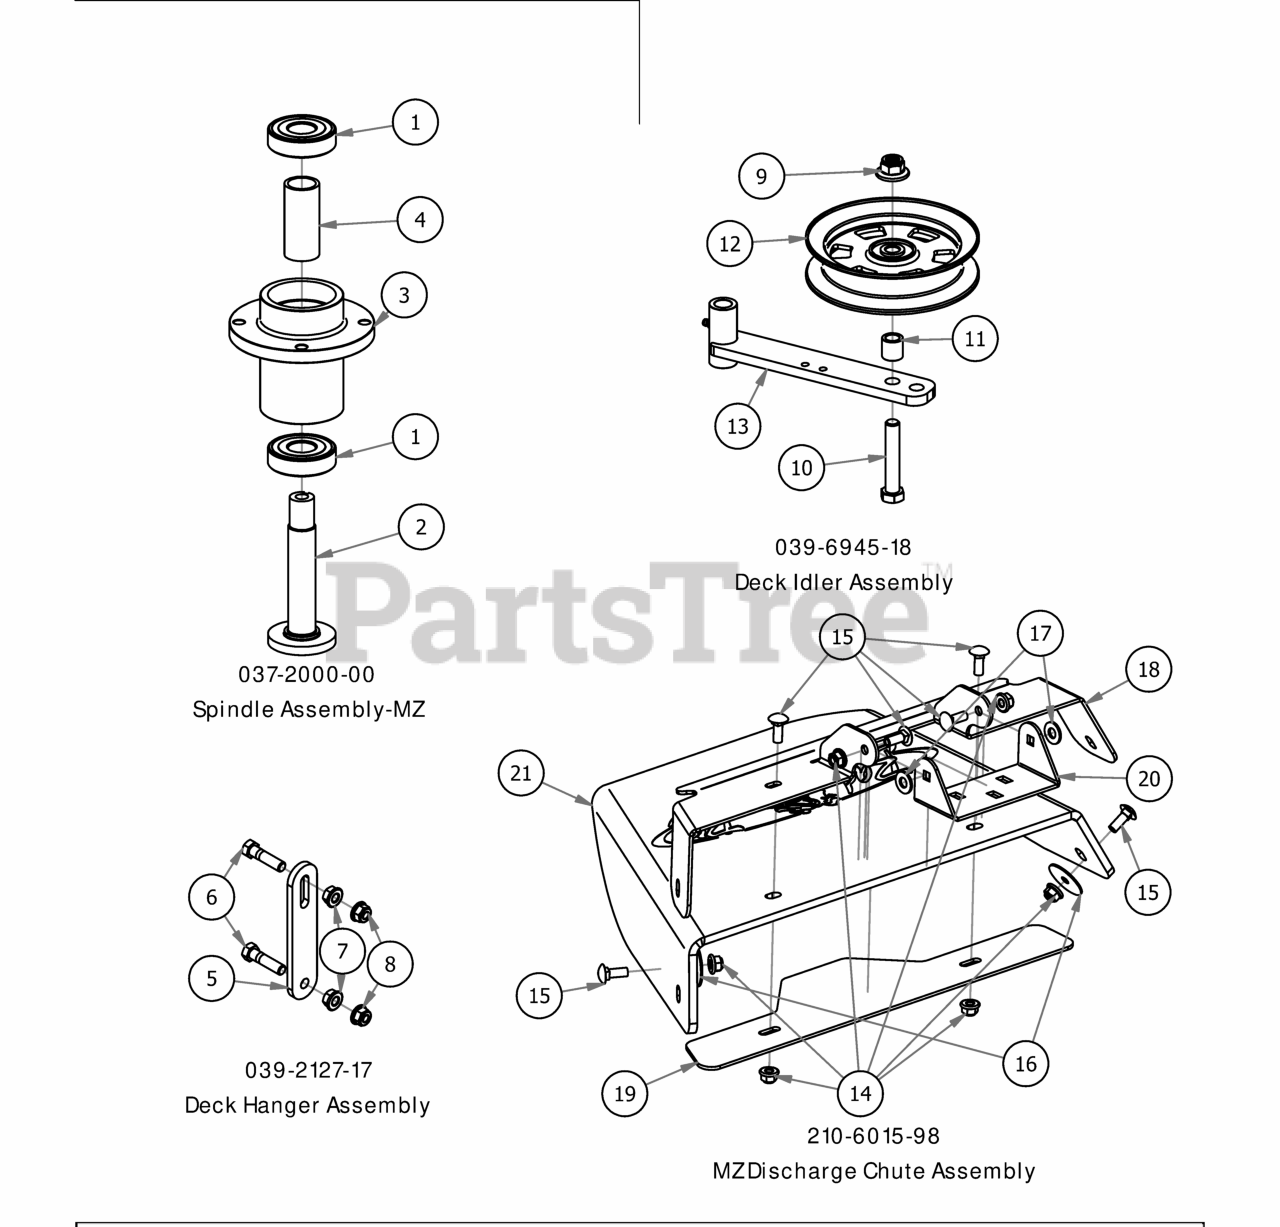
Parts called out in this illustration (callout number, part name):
1	Spindle Bearing
2	Spindle Shaft
3	Spindle Housing
4	Spindle Spacer-Component
5	2017 MZ/ZT Deck Hanger
6	3/8" x 1 1/2" Hex Bolt
7	3/8" Flange Nut
8	3/8" Nylock Flange Nut
9	1/2-13 Nylon Flange Nut
10	1/2" x 2 3/4" Hex Bolt
11	Spacer 3/4 OD x 1/2 ID x 3\4 Length
12	5" Idler Pully
14	5/16" Nylon Flange Nut
15	5/16" x 7/8" Carriage Bolt
16	5/16 Fender Washer
17	.360 ID Plastic Washer
18	Discharge Chute Bracket 48 MZ (Upper)
19	2017 MZ Discharge Chute Bracket-Lower
20	Chute Hanger 48 MZ
21	Rubber Discharge Chute MZ (Component)
